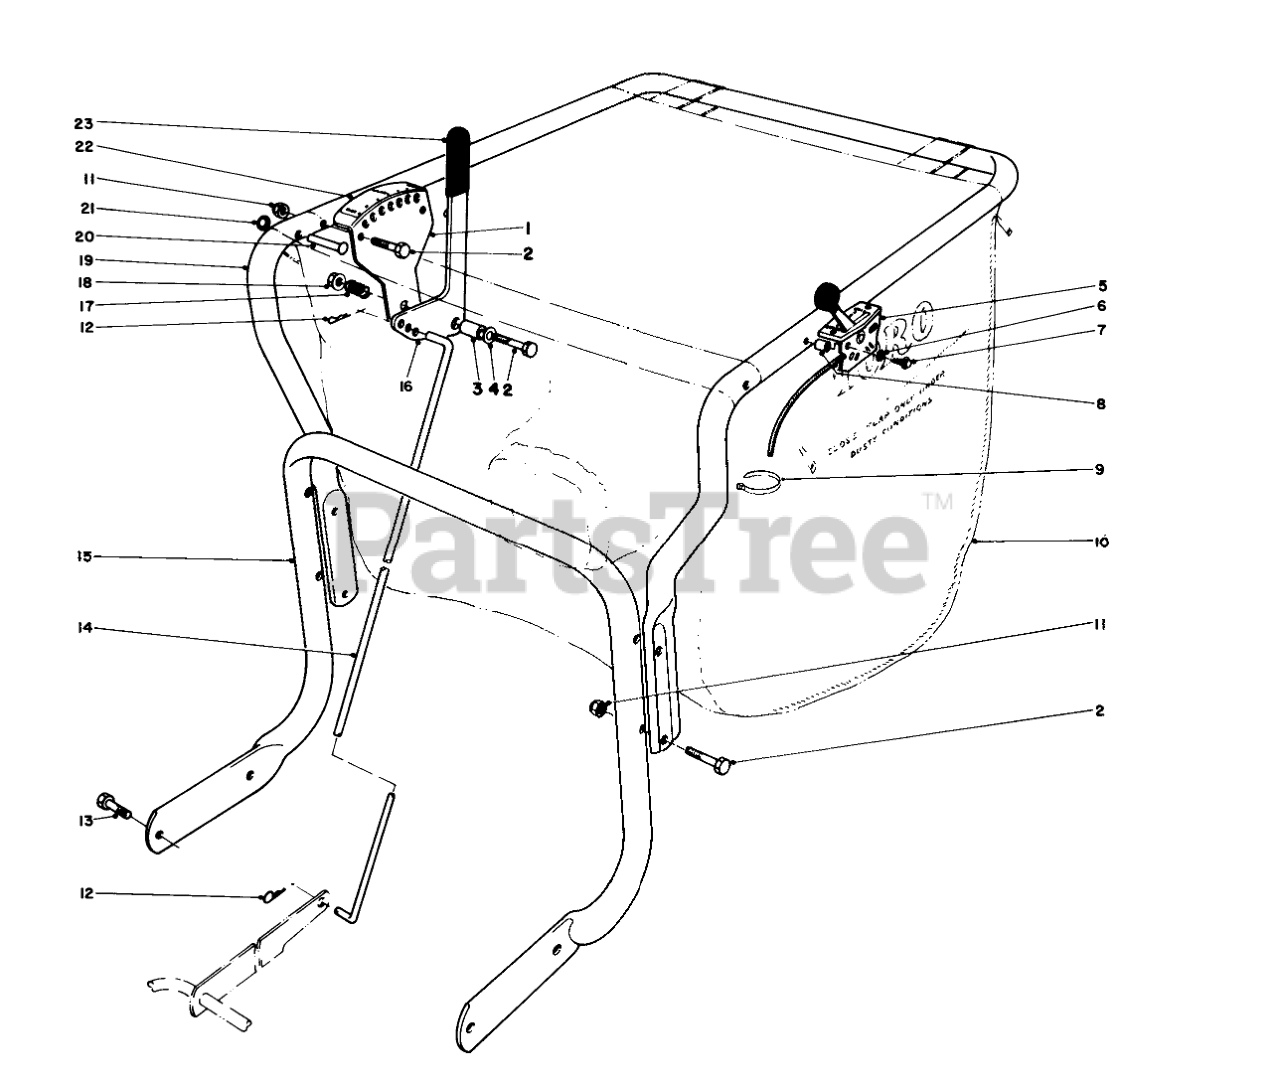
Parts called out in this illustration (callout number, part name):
1	Adjustment Bracket
2	SCREW-HH
3	SPACER
4	WASHER-FLAT
5	THROTTLE CONTROL
6	WASHER-LOCK, EXT
7	10-24 X 1 PAN HD SCR
8	SPACER
9	TIE-CABLE
10	Bag-Vacuum
11	NUT-LOCK, CONE
12	Hairpin Cotter
13	SCREW-HH
14	HEIGHT ADJ. ROD
15	HANDLE
16	Handle-Adjustment
17	SPRING-COMPRESSION
18	NUT-HF
19	HANDLE-UPPER, VACUUM
20	RIVET
21	NUT-PUSH IN
22	HT ADJ DECAL
23	GRIP-HANDLE
